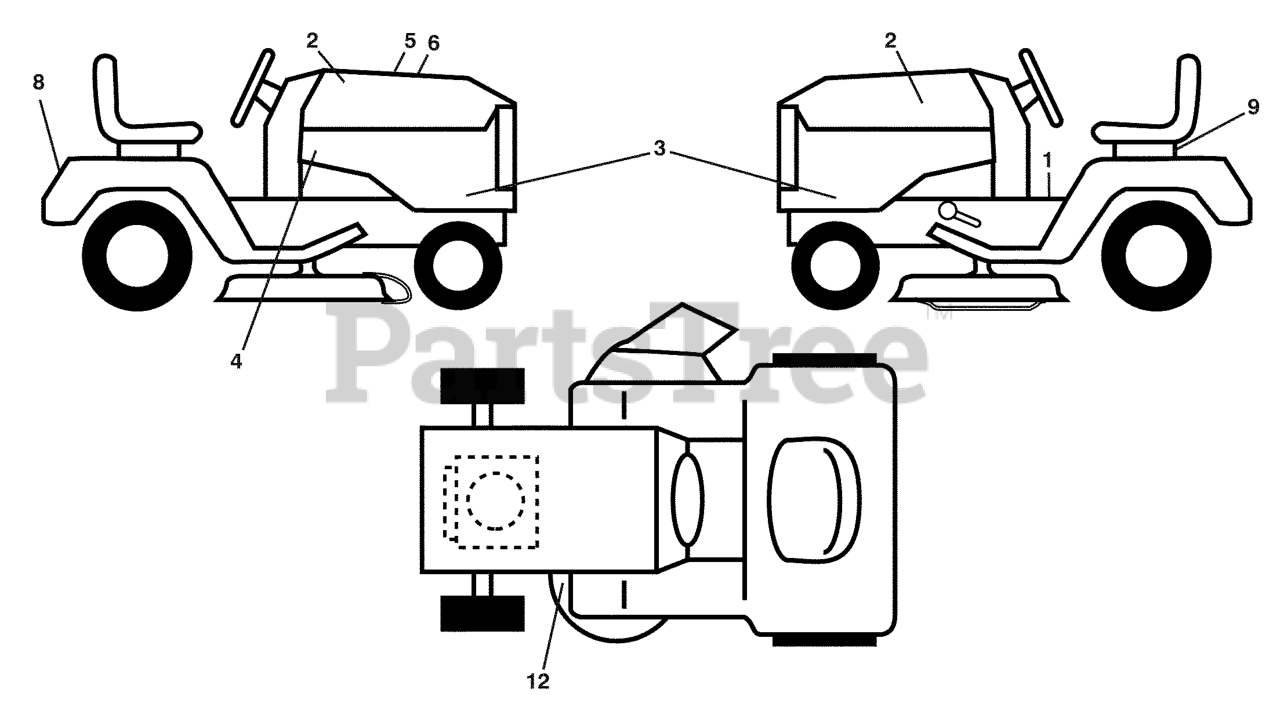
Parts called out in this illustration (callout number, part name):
1	DECAL.WARN.START.INSTRUCTIONS
2	RP EMBLEM, HOOD
3	DECAL.PNL.SD.YTH21K46.HUSQ.KOH
4	DECAL,ETHANOL E85 WARNING
5	DECAL.WARNING.CUST.RESP.E85.
6	Decal, Replacement
8	DECAL.FENDER
9	DECAL BTRY SYMBOLS
12	DECAL V BELT SCHEMATIC
